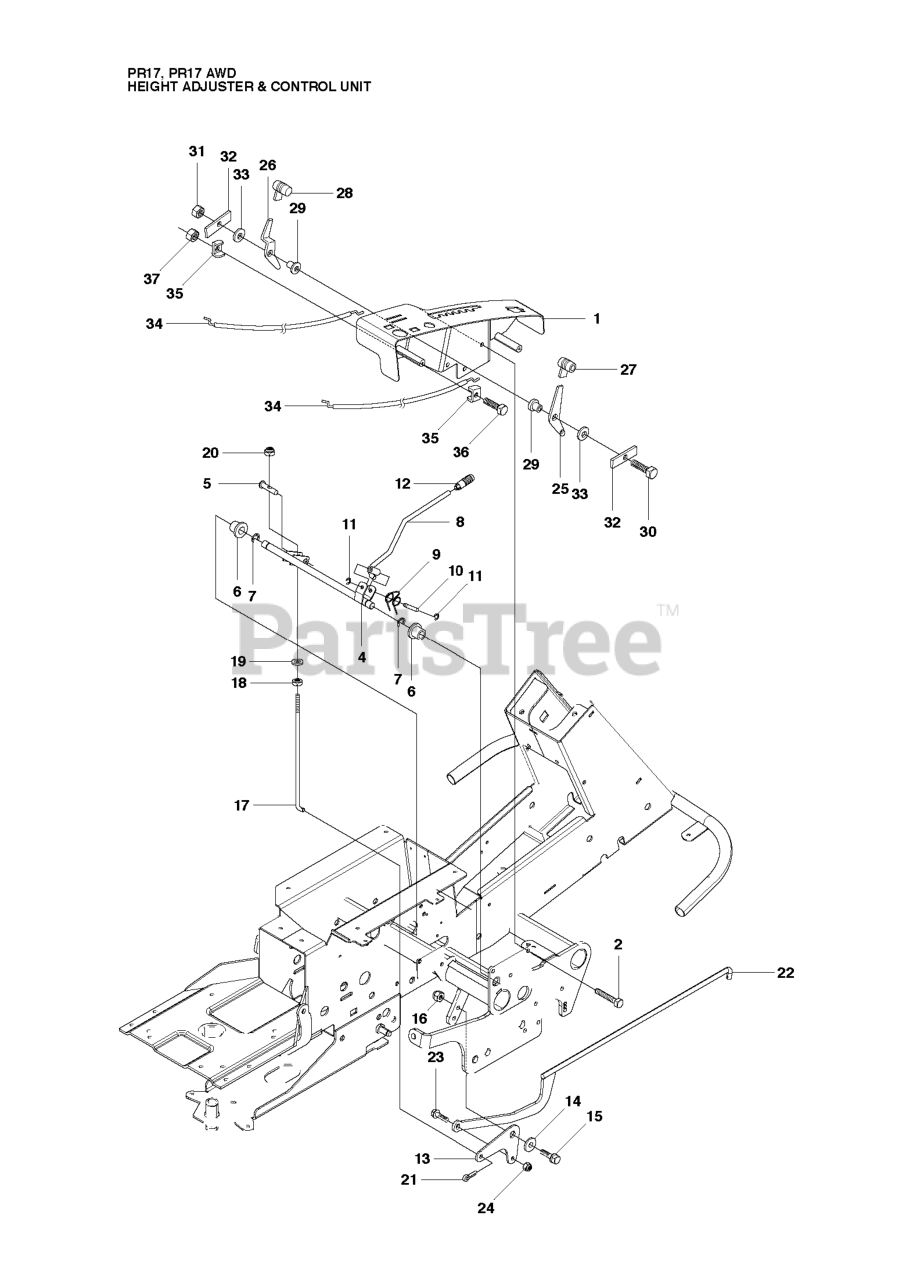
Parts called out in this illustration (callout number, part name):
6	BUSHING
9	HAIR PIN SPRING
12	GEAR STICK KNOB
14	WASHER
16	LOCKNUT M6
18	NUT
19	WASHER
20	LOCKNUT M8
24	NUT
30	SCREW M6S 6X30
31	LOCKNUT M6
33	SPRINGWASHER
37	LOCKNUT M5
